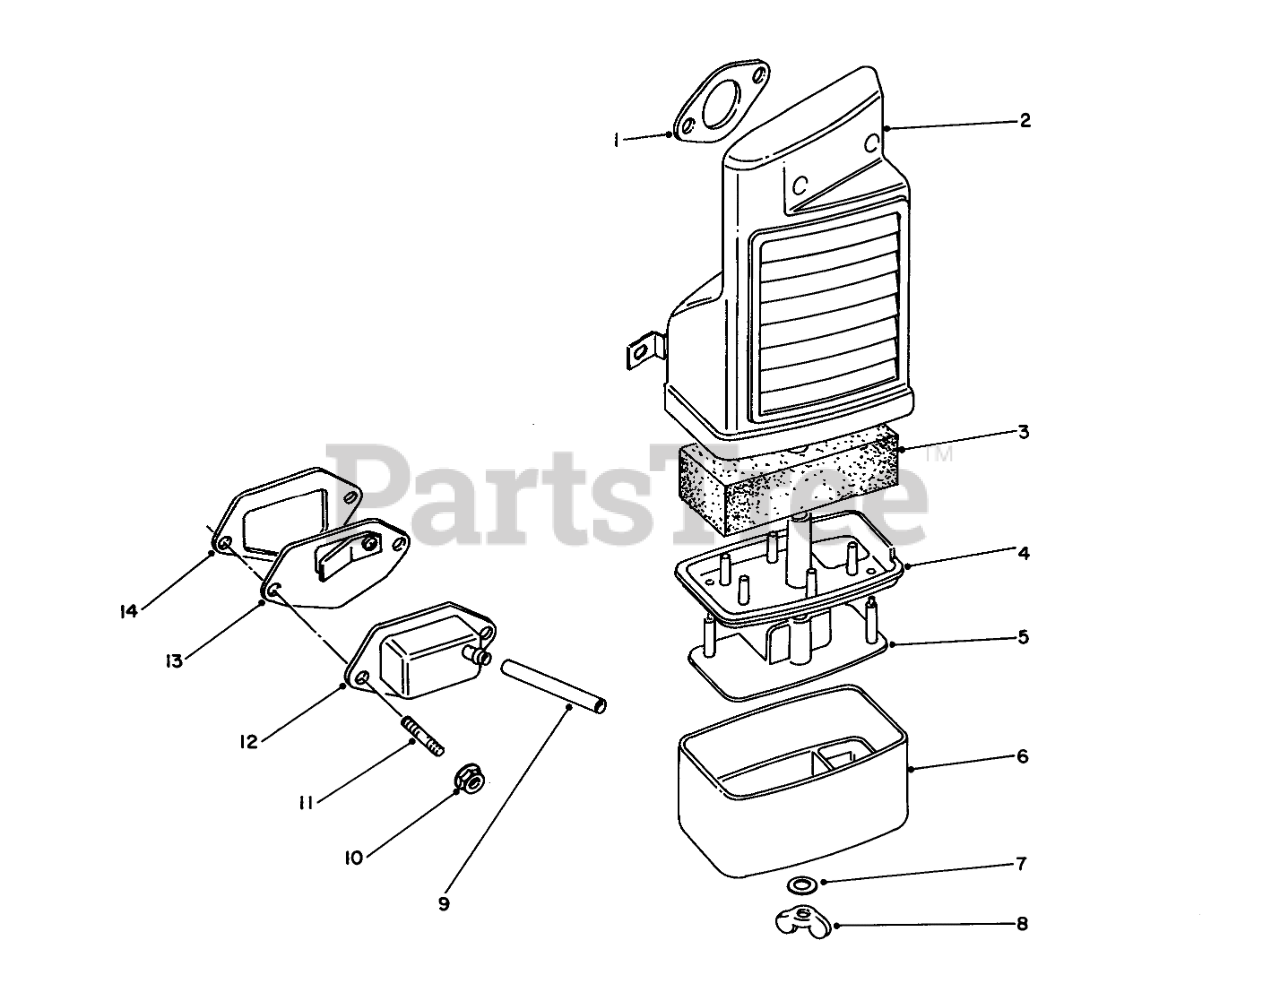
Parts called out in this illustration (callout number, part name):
1	GASKET
2	Air Cleaner Assembly (Incl. Ref. # 1 & 3-8)
3	FILTER
4	Partition (B)
5	Partition (A)
7	WASHER
9	Hose-Air Breather
11	Bolt-Stud
12	Cap-Breather
13	Reed Valve Assembly
14	Gasket
